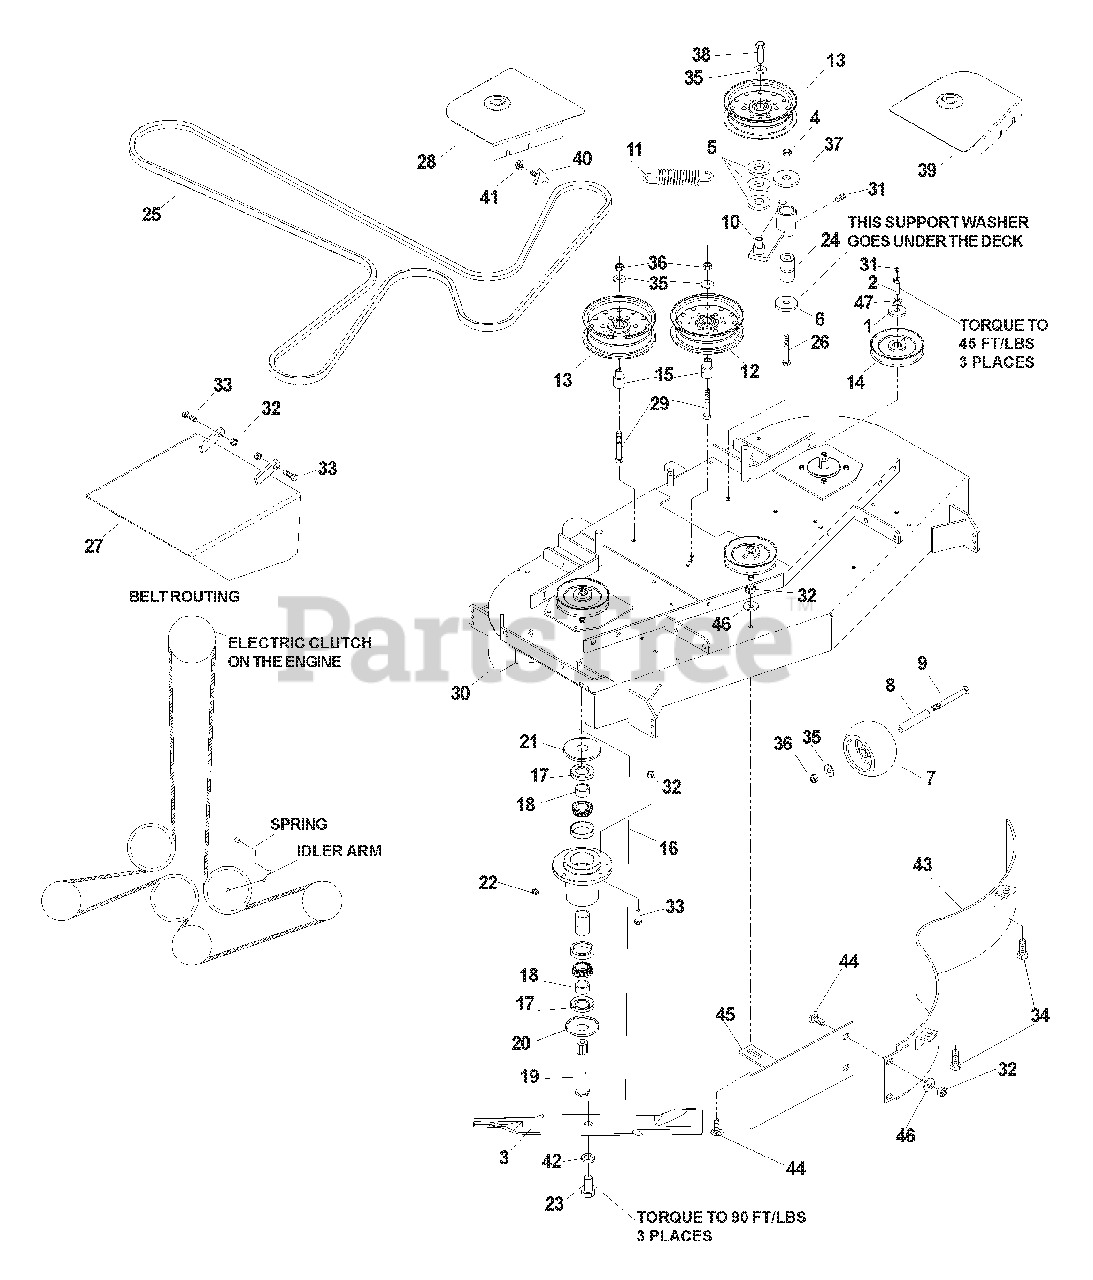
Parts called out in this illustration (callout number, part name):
1	HEAVY WASHER
2	HCS 7/16-20 X 1 1/2, SPECIAL
4	NUT, 1/2-13, NYLOC
5	BUSHING, MACHINE
6	SUPPORT WASHER
7	ANTI-SCALP ROLLER
9	HCS, 3/8-16 X 3 1/2
12	IDLER PULLEY
13	IDLER PULLEY (TALL)
14	PULLEY
15	IDLER BUSHING
16	SPINDLE, COMPLETE
17	SHAFT SEAL
19	SPINDLE
20	DUST CAP, BOTTOM
21	DUST CAP, TOP
22	GREASE POPET
23	HCS, 5/8-18 X 1 1/4
24	PIVOT BUSHING
26	HCS, 1/2-13 X 3 1/4
27	DEFLECTOR CHUTE
28	SHIELD, RIGHT
29	HCS, 3/8-16 X 2 1/2
30	DECK W/DECALS
31	ZERK
32	NUT, 5/16-18, CENTER LOCK
33	HCS, 5/16-18 X 1
34	HCS, 5/16-18 X 3/4
35	WASHER 3/8 FLAT
36	NUT, 3/8-16 CENTER LOCK
37	WASHER, 1/2
38	HCS, 3/8-16 X 1, SERR. HD.
39	SHIELD, LEFT
40	KNOB
42	LOCKWASHER, 5/8
43	BAFFLE, MAIN
44	RHSNB, 5/16-18 X 5/8
45	BAFFLE, CENTER
46	WASHER, 5/16
47	LOCKWASHER, 7/16
